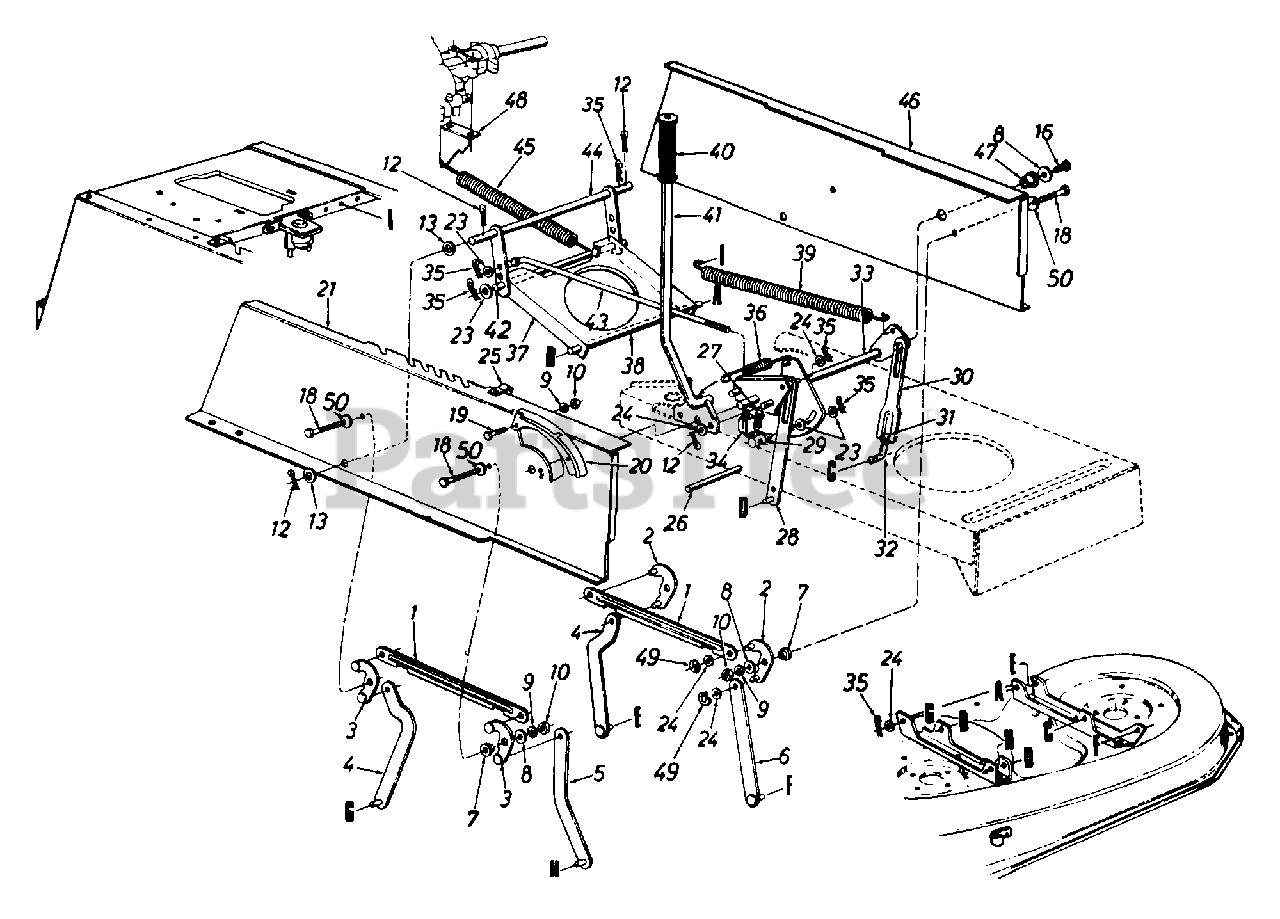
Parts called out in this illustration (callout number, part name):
1	Connecting Rod
2	Pivot Link Ass'y. - L.H.
3	Pivot Link Ass'y. - R.H.
4	Deck Hanger Link Ass'y.
5	Deck Hanger Link Ass'y.
6	Deck Hanger Link Ass'y.
7	Shld. Spacer .318" I.D.
8	Fl-Wash. .344" I.D. x .62" O.D.
9	L-Wash. 5/16" I.D.
10	Hex Nut 5/16-18 Thd.
12	Cotter Pin 1/8" Dia.
13	Fl-Wash. .635" I.D. x 1.0" O.D.
16	Hex Wash. TT-Tap Scr. 5/16-18 x .75" Lg.
18	Hex Wash. Hd. Scr. 5/16-18 x .875" Lg.
19	Hex Bolt 5/16-18 x .75" Lg.
20	Index Brkt.
24	Fl-Wash. .531" I.D. x .93" O.D.
25	Clamp
26	Running Board Rod
27	Hex Wash. Hd. Tap Scr.
28	Link Deck Lift Ass'y.
29	Adj. Ferrule 3/8-24 Thd.
30	Adj. Deck Lift Link
31	Hex Nut 1/2-20 Thd. (Gr. 5)
32	Lift Link Adjuster
33	Lift Shaft Ass'y.
34	Safety Switch (Deck)
35	Inter. Cotter Pin 3/8" Dia.
36	Extension Spring
37	Stabilizer Bracket
38	Shaft 1/2" Dia. x 10.28" Lg.
39	Extension Spring
40	Grip (Lift Handle)
41	Deck Lift Handle Ass'y.
42	Shaft 3/8" Dia. x 9.34" Lg.
43	Disengagement Rod
44	Stabilizer Shaft Ass'y.
45	Extension Spring 7.58" Lg.
48	Spring Retainer Brkt.
49	E - Ring
50	Bell-Wash. .325" I.D.
